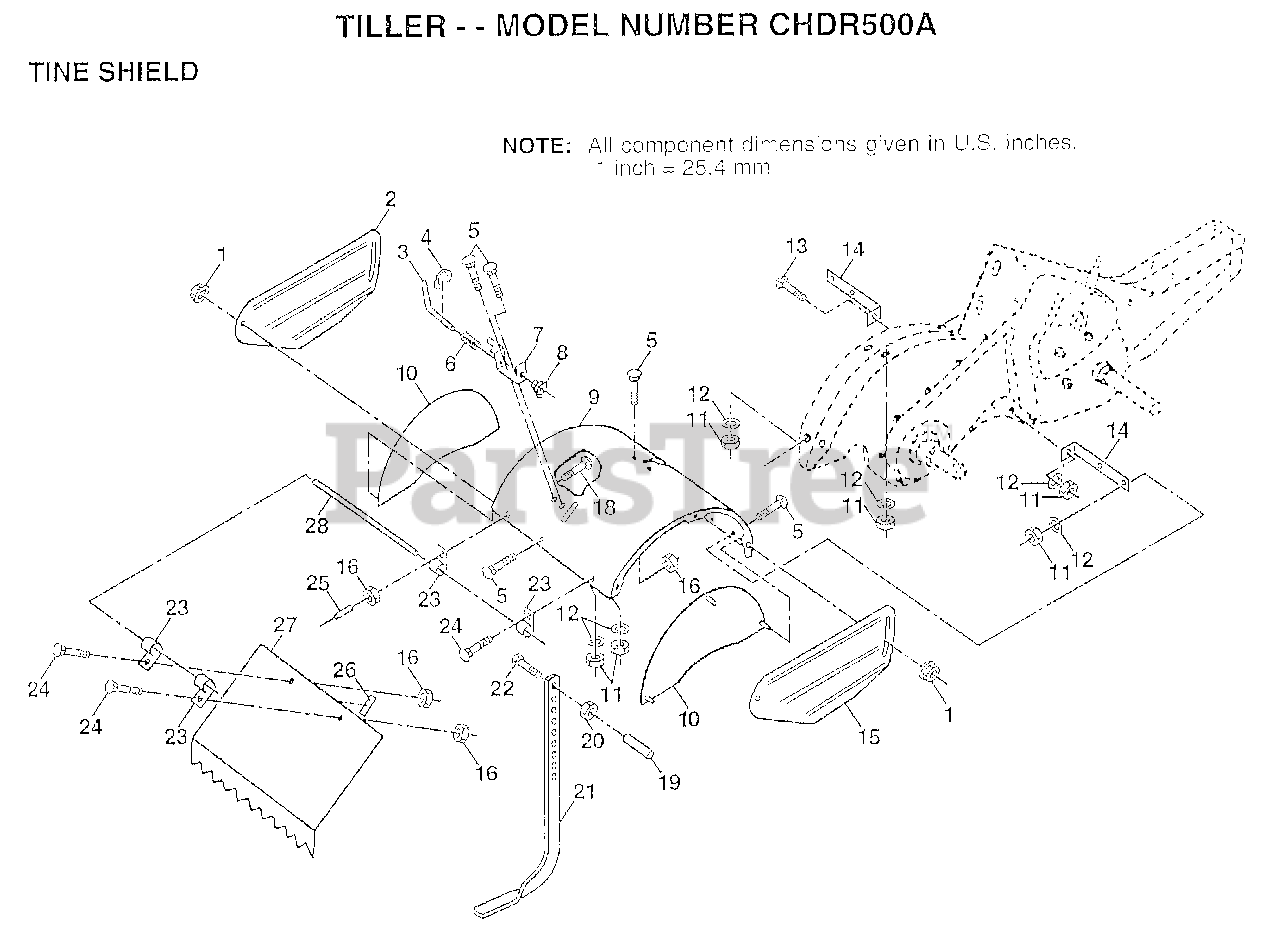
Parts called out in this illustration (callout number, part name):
1	NUT
2	SHIELD.SD.OUT.LH
3	STAKE PIN TI
4	KLIP RING TI
5	BOLT
6	SPRING TI
7	LATCH BRACKET TI
8	SPRING CRT
9	SHIELD TINE
10	SHIELD SIDE
11	NUT.HEX.5/16-18
12	LOCKWASHER
13	BOLT
14	BRKT SHIELD TINE
15	"SHIELD TINE,SIDE"
16	NUT
18	BOLT
19	GRIP CRT
20	NUT.HEX.3/8-16UNC
22	BOLT
23	HINGE CRT
24	BOLT
25	VINYL CAP TI
26	PAD IDLER TI
27	"SHIELD,LEVEL"
28	PIN HINGE
